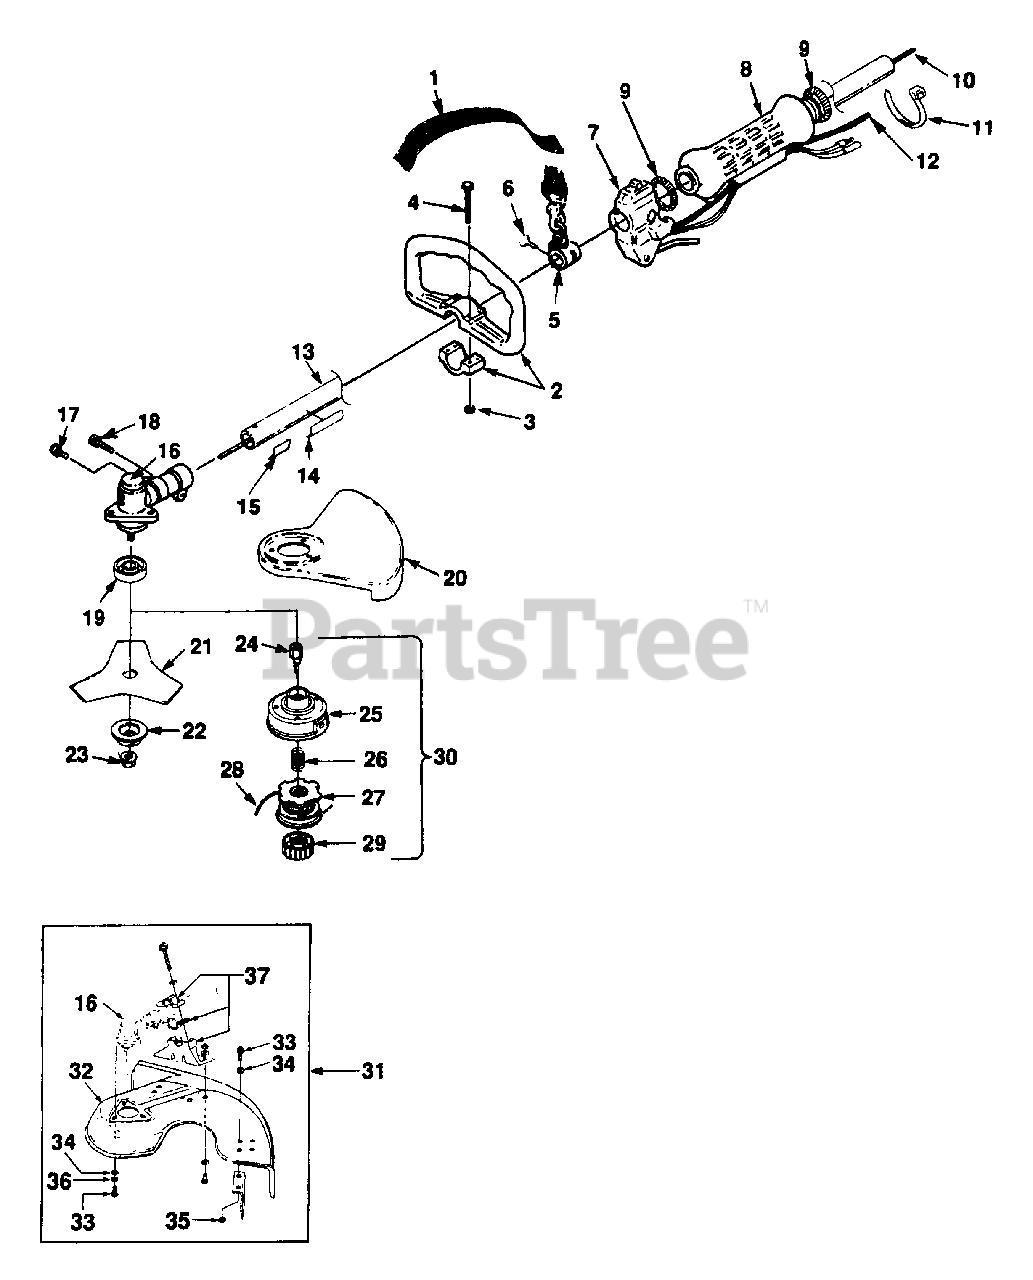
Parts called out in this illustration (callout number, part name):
1	HARNESS w/Connector
2	HANDLE-Front
3	NUT-Hex (M5 X 0.8)
4	SCREW-Hex Hd (M5 X 0.8 X 35)
5	BRACKET-Hanger
6	SCREW-Thumb (10-24 X 1/2")
7	THROTTLE & SWITCH w/Lead
8	GRIP-Handle
9	SPRING-Tension
10	SHAFT-Drive
11	CABLE-Tie
12	CABLE-Throttle
13	HOUSING-Drive Shaft (Black)
14	DECAL-Starting Instructions
15	DECAL-Warning
16	GEAR HEAD
17	SCREW-Sems Hex Hd (10-24 X 1/2")
18	SCREW-Cap Socket Hd (1/4-20 x 7/8")
19	WASHER-Flange
20	GUARD-Blade
21	BLADE-Tri-Arc
22	WASHER-Flange
23	NUT-Hex (L.H.)
24	CONNECTOR-Drive
25	HOUSING & EYELET (Dual Line)
26	SPRING-Compression
27	SPOOL & STRING (Dual Line)
28	LINE-Replacement (1 lb Box, .095" Dia.)
29	RETAINER-Spool (L.H.) (Red)
30	STRINGHEAD COMPLETE
31	GRASS DEFLECTOR KIT
32	DEFLECTOR & BLADE
33	SCREW-Mach Hex Hd
34	WASHER-Flat
35	NUT-Hex (10-24)
36	WASHER-Lock
37	DEFLECTOR BRACKET KIT
